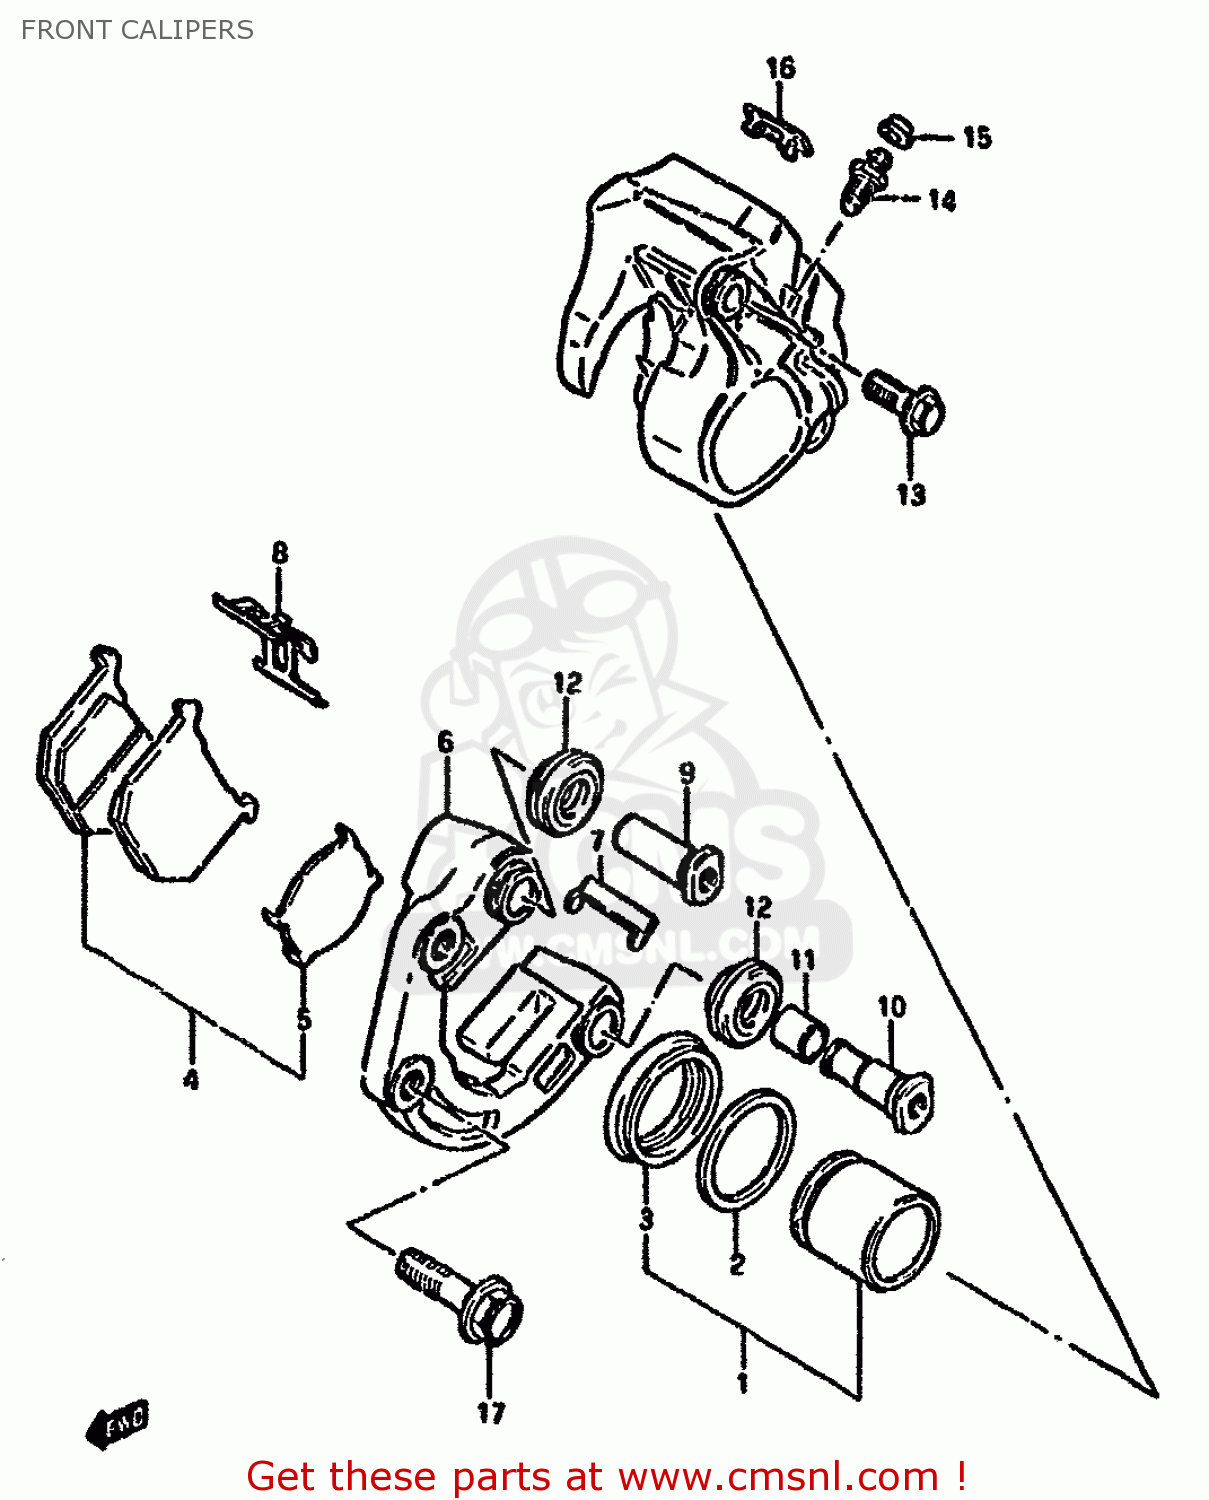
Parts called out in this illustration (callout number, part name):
1	PISTON SET
2	SEAL,PISTON
3	BOOT,PISTON
4	PAD
5	SHIM,PAD
6	CALIPER SET,CARRIER,L
7	GUIDE,PAD
8	SPRING,PAD
9	AXLE NO.1
10	AXLE NO.2
11	BUSH,AXLE
12	BOOT,AXLE
13	BOLT
14	BLEEDER
15	CAP,BREATHER
16	COVER
17	BOLT
